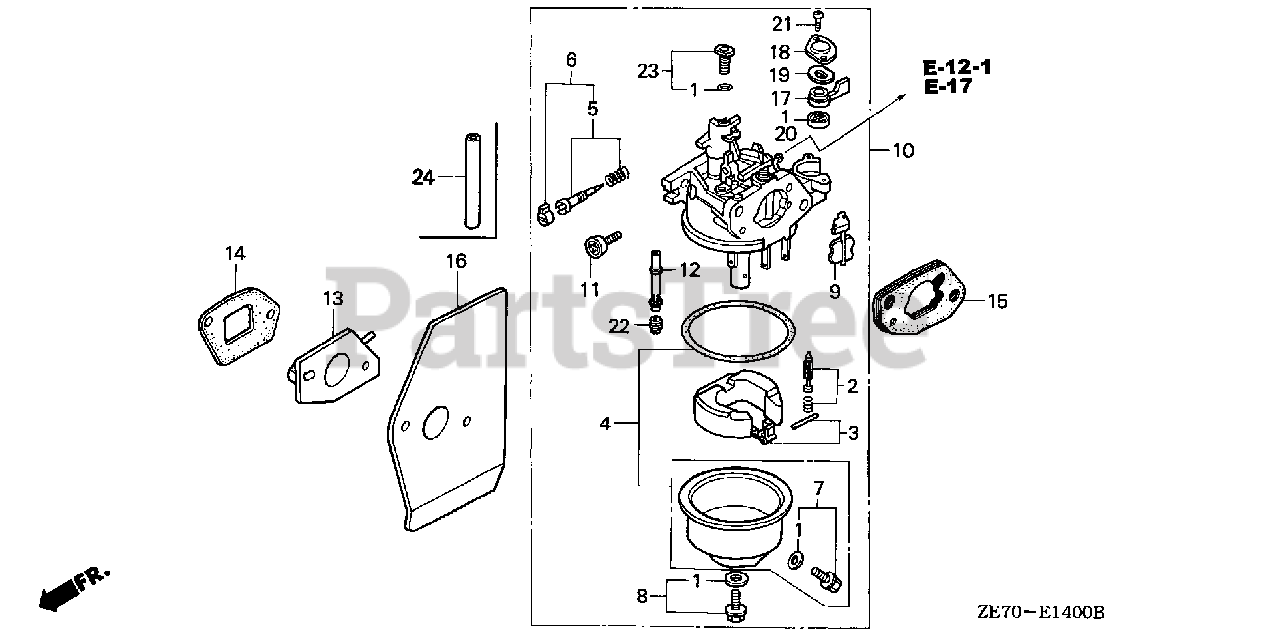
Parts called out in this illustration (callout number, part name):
1	GASKET SET
2	VALVE SET, FLOAT
3	FLOAT SET
4	CHAMBER SET, FLOAT
6	SCREW SET
7	SCREW SET, DRAIN
8	SCREW SET B
9	CHOKE SET
10	CARBURETOR ASSY. (BE66C B)
11	SCREW, THROTTLE STOP
12	NOZZLE, MAIN
13	INSULATOR, CARBURETOR
14	GASKET, INSULATOR
15	SPACER, CARBURETOR
16	GASKET, CARBURETOR
17	LEVER, VALVE
18	PLATE, LEVER SETTING
19	SPRING, VALVE LEVER
20	GASKET, VALVE
21	SCREW, PAN (3X6)
21	SCREW, PAN (3X8)
22	JET, MAIN (#60)
22	JET, MAIN (#62)
22	JET, MAIN (#65)
23	JET SET, PILOT (#35)
